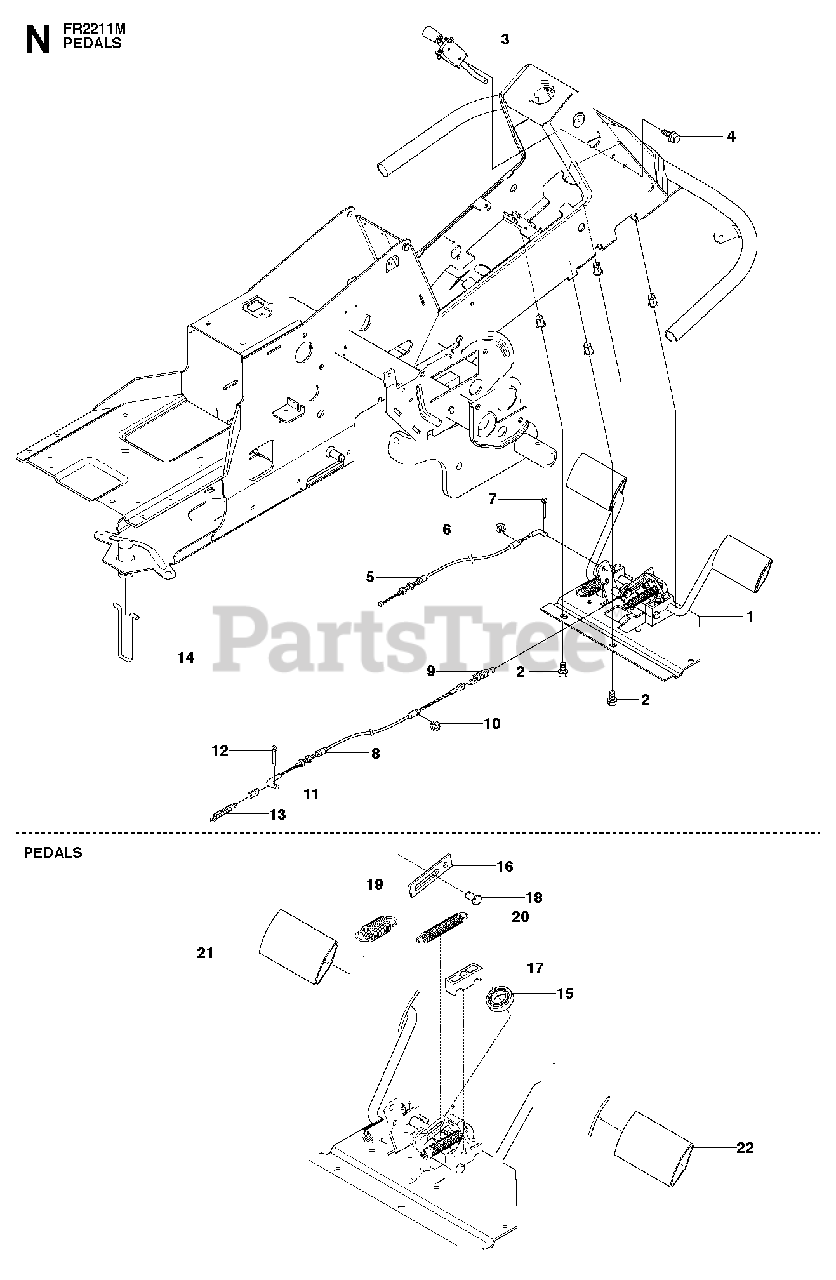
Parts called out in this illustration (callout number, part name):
3	BRAKE LEVER ASSY
7	COTTER PIN
11	CONNECTOR
12	COTTER PIN
15	BALL BEARING 6002-2RS1
17	PEDAL SHAFT CLAMP
18	CLEVIS PIN
21	PEDAL RUBBER, SF
22	PEDAL RUBBER, SF
